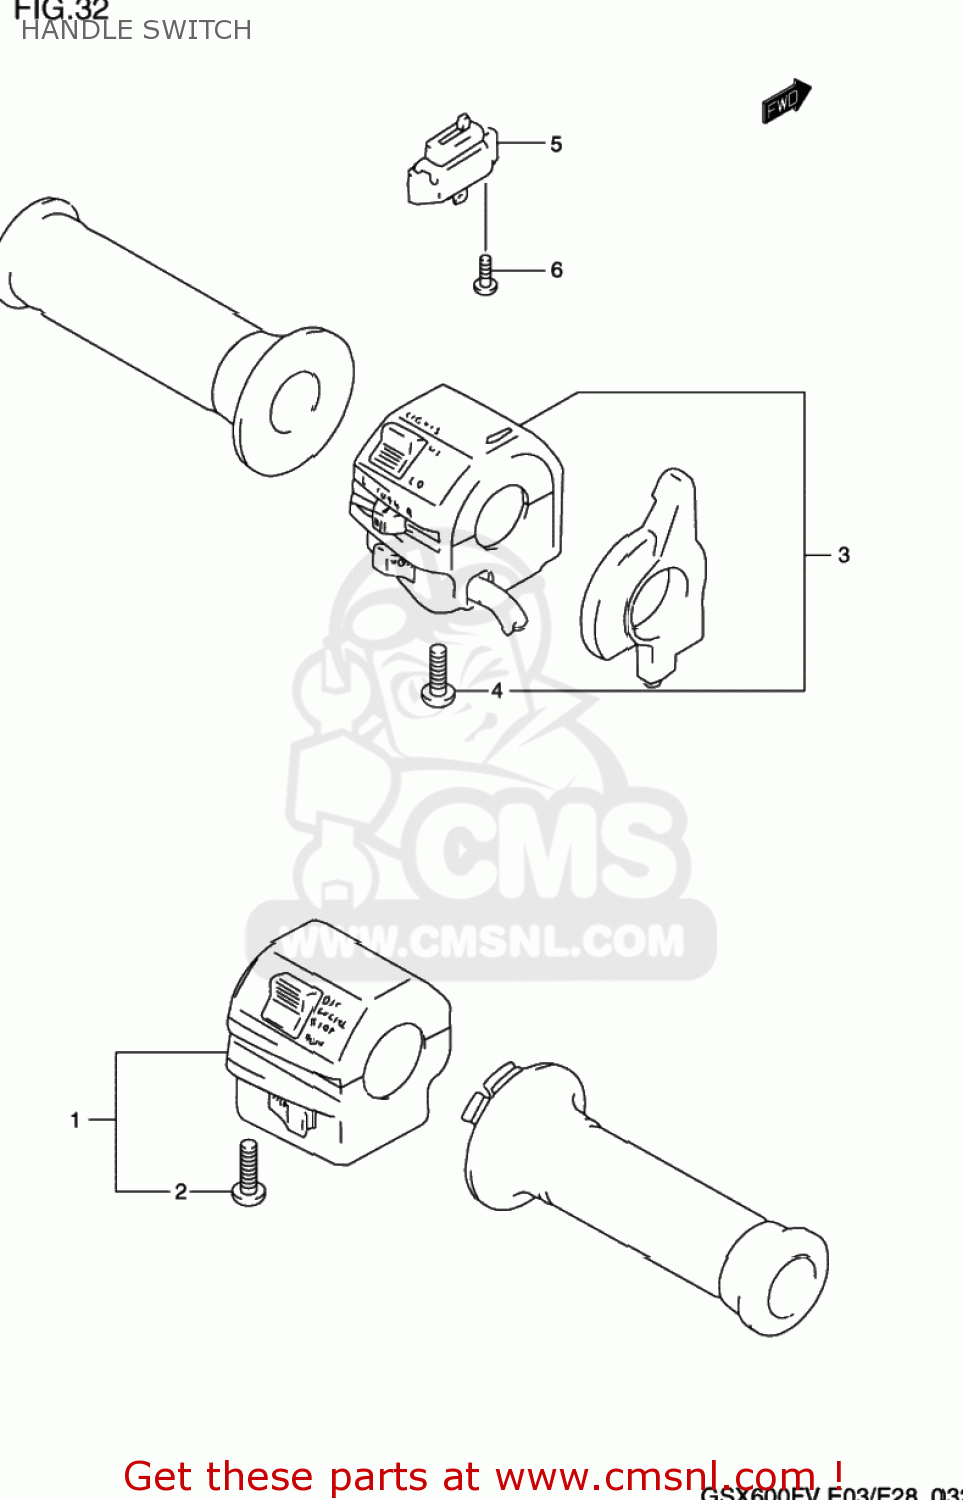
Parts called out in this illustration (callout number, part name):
1	SWITCH ASSEMBLY,HANDLE,RIGHT
2	SCREW, 5X45
3	SWITCH ASSY, HANDLE,LH
4	SCREW, 5X45
5	SWITCH ASSY,CLUTCH
6	SCREW
